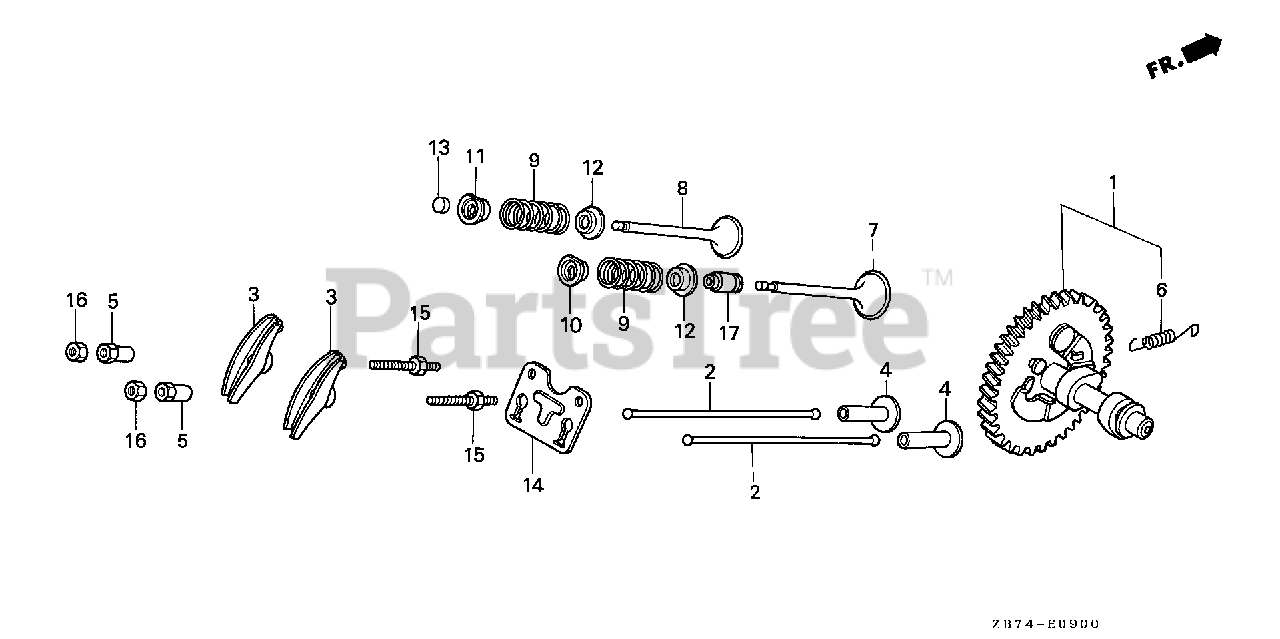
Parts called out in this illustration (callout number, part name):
1	CAMSHAFT ASSY.
2	ROD, PUSH
3	ARM, VALVE ROCKER
4	LIFTER, VALVE
5	PIVOT, ROCKER ARM
6	SPRING, WEIGHT RETURN
7	VALVE, IN.
8	VALVE, EX. (STELLITE)
9	SPRING, VALVE
10	RETAINER, IN. VALVE SPRING (EXHAUST SIDE)
11	RETAINER, EX. VALVE SPRING
12	SEAT, VALVE SPRING
13	ROTATOR, VALVE
14	PLATE, PUSH ROD GUIDE
15	BOLT, PIVOT (8MM)
16	NUT, PIVOT ADJ.
17	SEAL, VALVE STEM
